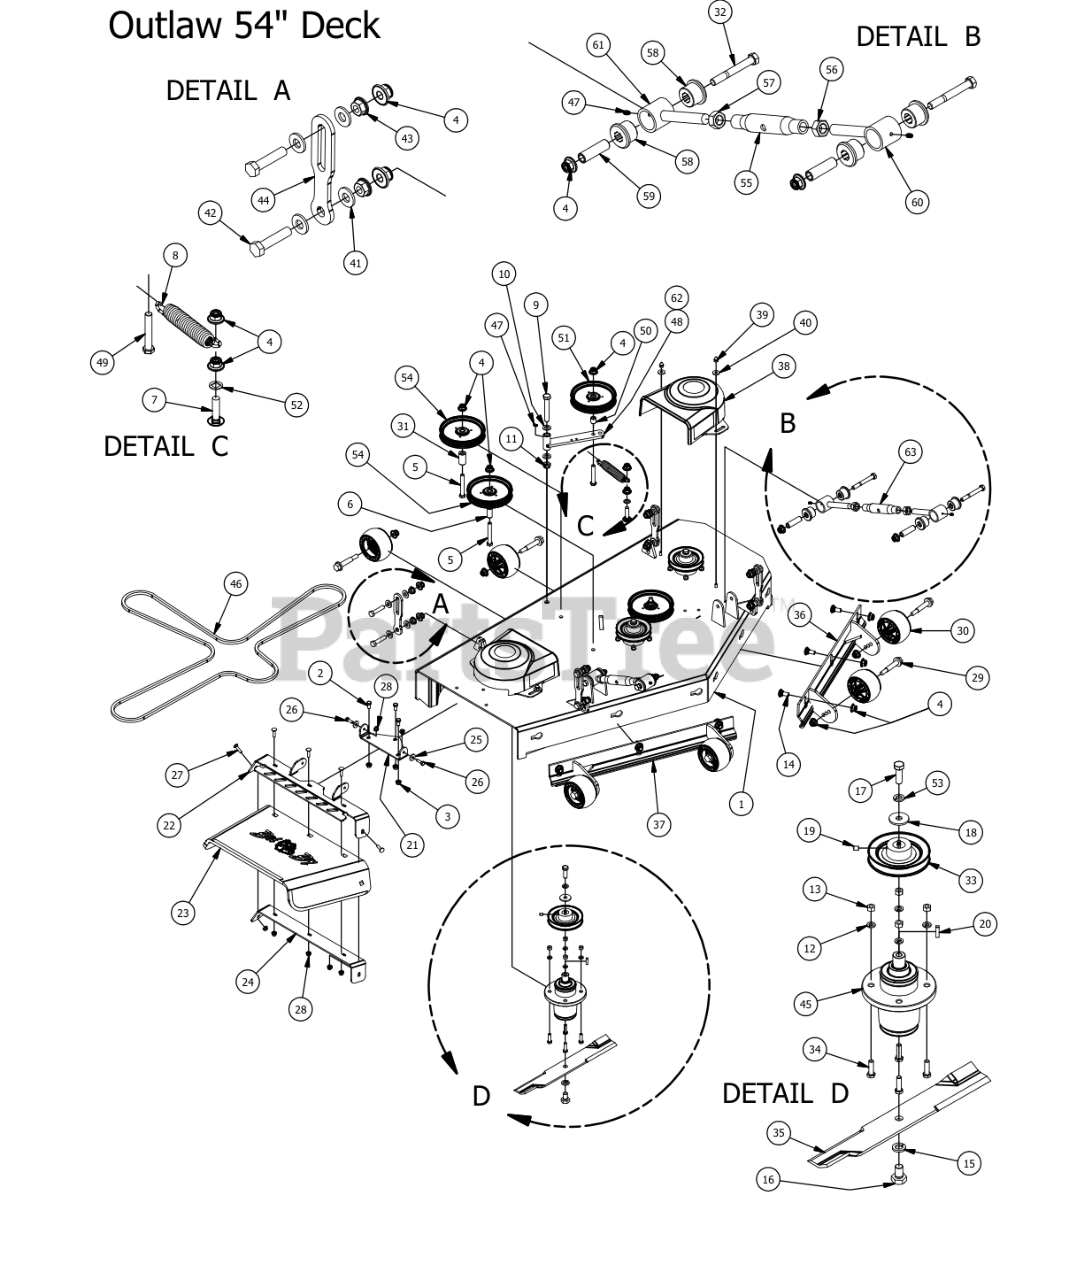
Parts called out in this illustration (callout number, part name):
1	2015 54" Deck
2	3/8" x 3/4" Hex Bolt
3	3/8" Flange Nut
4	1/2-13 Nylon Flange Nut
5	1/2 x 3 1/2 Flange Bolt Grade 8
6	.502 ID X.750 OD X 1.500 Long Spacer
7	1/2 x 2" Carriage Bolt
8	2015 Deck Idler Spring Outlaws
9	5/8" x 4" Hex Bolt
10	.630 ID Plastic Washer
11	5/8-11 Nylon Insert Jam Half Nut
12	3/8 Lockwasher Zinc
13	3/8-16 Hex Nuts Zinc
14	1/2" x 1 1/4 Carriage Bolt
15	5/8" Lock Washer
16	5/8" x 1 1/2" Grade 8 Hex Bolt (Fine)
17	1/2"-20 x 1 1/2 - Grade 5 Fine Thread Bolt
18	1/2 Belleville Washer
19	5/16 Set Screw
20	1/4" x 1" Key
21	Discharge Chute Hanger (deck mounted)
22	60" Discharge Chute Upper Hanger
23	Rubber Discharge Chute
24	60" Discharge Lower Bracket
25	.360 ID Plastic Washer
26	5/16" x 1" Bolt
27	5/16" x 1 1/4" Carriage Bolt
28	5/16" Nylock Flange Nut Zinc
29	Deck Wheel Bolt
30	Anti-Scalp Rollers
31	1 3/4" Pulley Spacer
32	1/2" x 4" Bolt (Grade 8)
33	5" Spindle Deck Pulley
34	3/8" x 1 1/4" Hex Bolt
35	54" Deck Fusion Blade For Outlaw
36	54 Deck Adustable Front (Left)
37	54 Deck Adustable Front (Right)
38	Pulley Cover
39	Acorn nut-pulley Cover
40	.360 ID Plastic Washer-Black
41	.505 Nylon Spacer
42	1/2-13X 2-1/4 GR Hex Bolts
43	1/2" Flange Nut
44	Deck_Hanging_Tab
45	OUTLAW SPINDLE ASSEMBLY
46	60" ZT Deck Belt
47	1/4" Press in Grease Fitting
48	Deck Idler
49	1/2-13 x GR 5 Hex Bolt Zinc
50	Spacer 3/4 OD x 1/2 ID x 3\4 Length
51	5-3/4 Idler Pulley-Don Dye
52	.517 Square Hole Round Washer
53	1/2" Lock Washer
54	5-3/4 Idler Pulley-Capitol Stampings
55	2015 Outlaw Toplink Body
56	3/4-10 Left-Handed Hex Nuts Zinc
57	3/4-10 Hex Nuts Zinc
60	Turn Left-Handed
61	Right-Handed End
62	Deck Idler Assembly - Includes parts: 4,47,48,50,51
63	Turnbuckle Assembly
